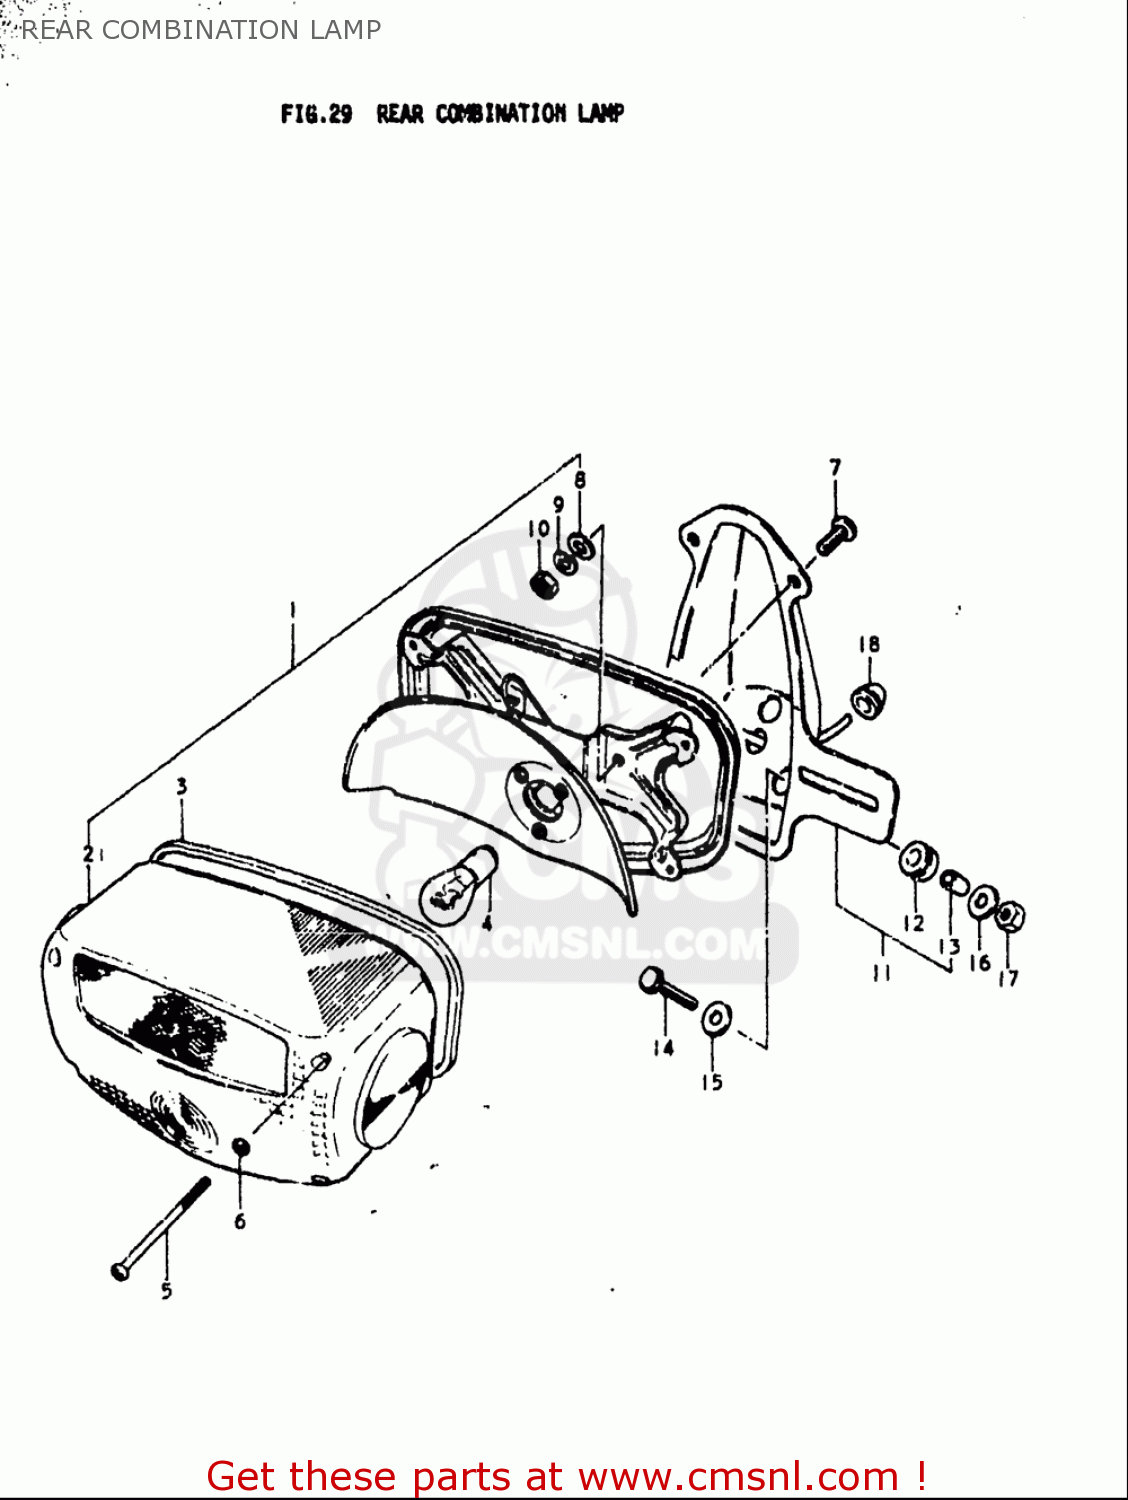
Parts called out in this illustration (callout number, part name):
1	LAMP UNIT,REAR COMBINATION
2	LENS
3	GASKET (NAS)
4	BULB(12V23W)
6	GASKET (NAS)
7	SCREW
8	WASHER
9	WASHER,LOCK
10	NUT
12	CUSHION
13	SPACER
14	BOLT
15	WASHER(6.5X20X1.2)
16	WASHER
17	NUT
18	GROMMET
